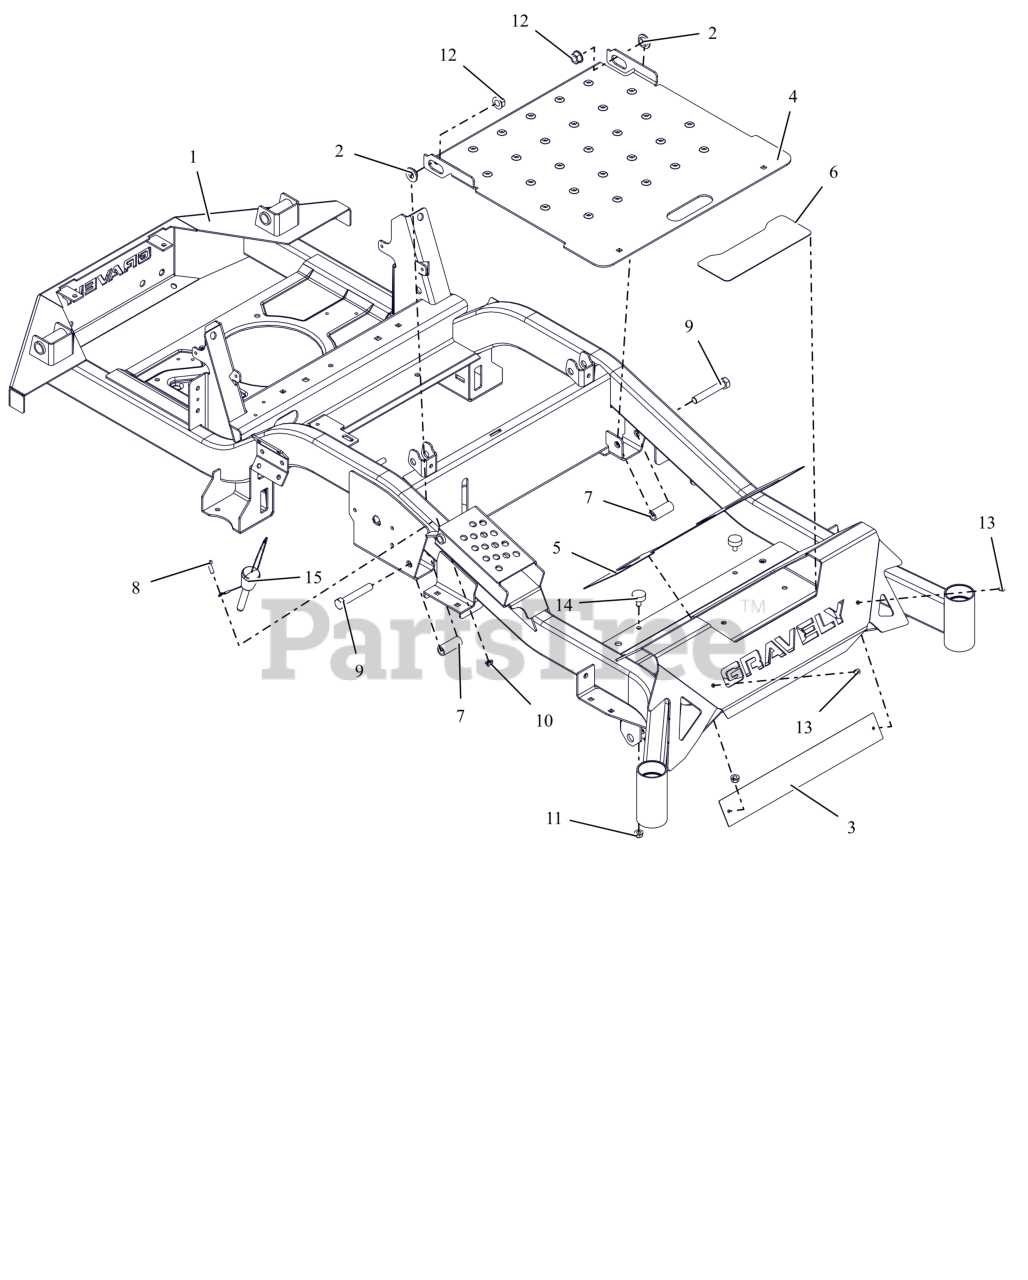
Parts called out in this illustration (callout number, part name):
1	HD 44-52 FRAME W/SAFETY DECALS
2	BSHG-FLG .515X.750X.310X1.120
3	PLATE, BACK FOOT-REST XL
4	KIT,ACCESS PANEL W/DECALS-RED
5	GRIP, FRONT
6	GRIP, STEP
7	SPACER, .515X.75X1.83
8	BLT, HEX .25-20X.75 G5 ZCC
9	BLT, HEX .50-13X3.00 G5 ZCC
10	NUT,NYL-FLG .25-20 GF ZCC
11	NUT,SPNLK-FLG .31-18 G5 ZCC
12	NUT-LK-TOP-FLG .500-13 GF ZCC
13	RIVET, .1875 AL/AL .126-.250
14	BUMPER, RUBBER
15	PIN, MAGNETIC .50X2.50
